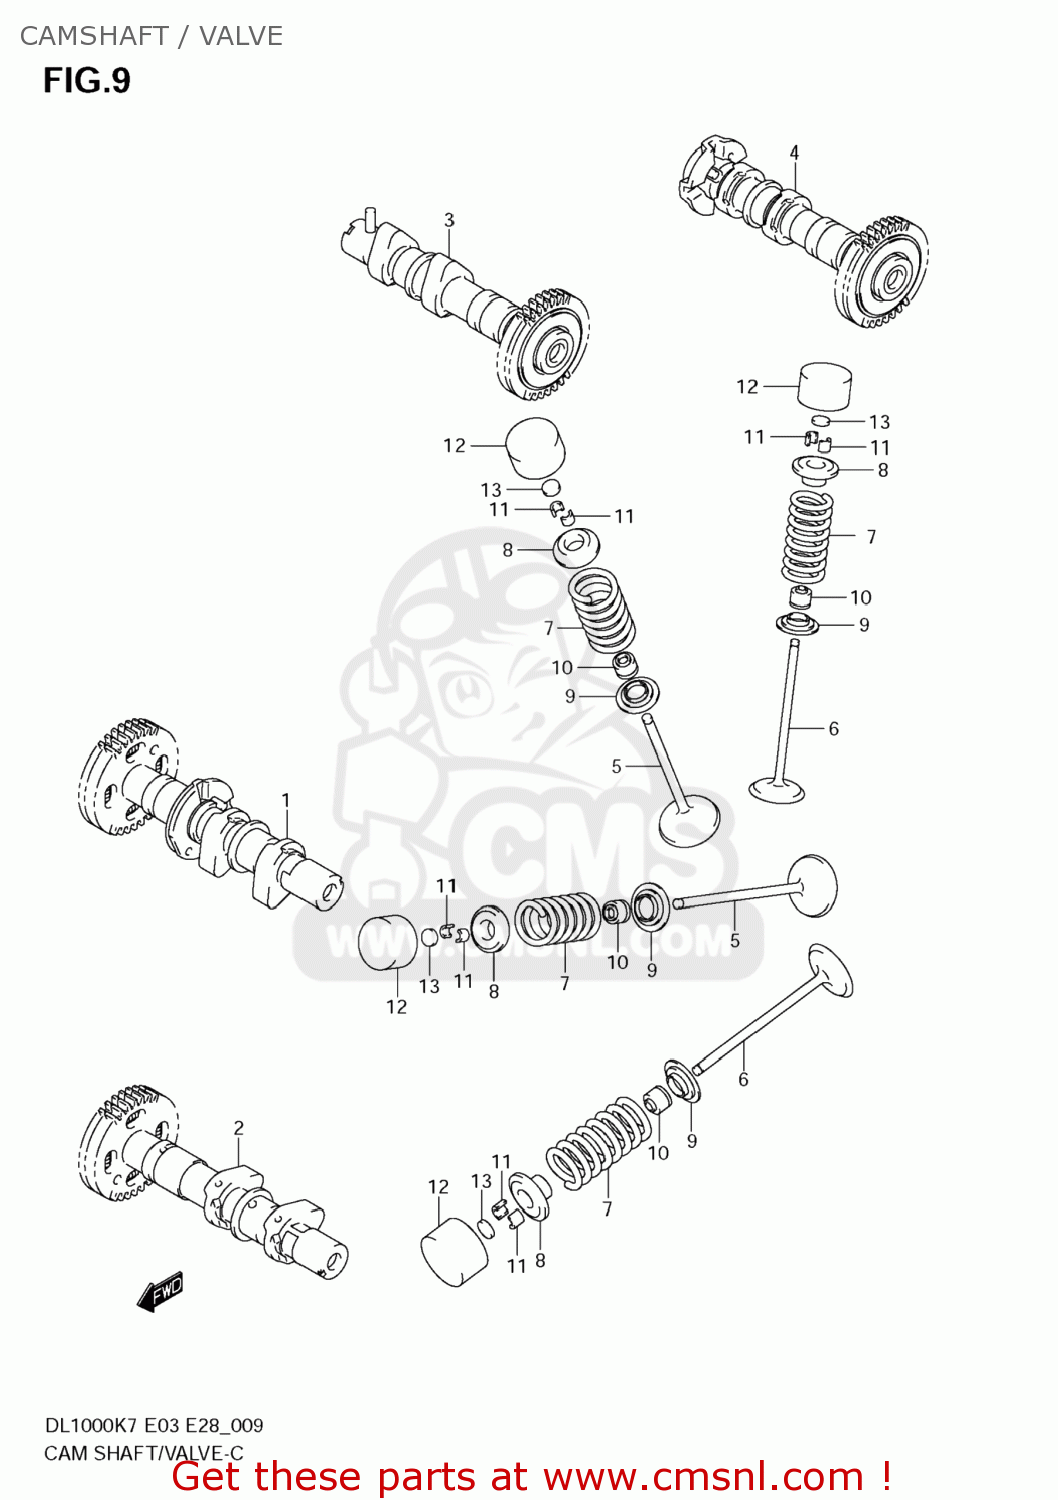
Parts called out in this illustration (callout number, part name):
1	CAMSHAFT ASSY,INTAKE FR
2	CAMSHAFT ASSY,EXHAUST FR
3	CAMSHAFT ASSY,INTAKE RR
4	CAMSHAFT ASSY,EXHAUST RR
5	VALVE,INTAKE
6	VALVE,EXHAUST
7	SPRING,VALVE
8	RETAINER,VALVE SPRING
9	SEAT,VALVE SPRING
10	SEAL,OIL(5.5X11X8.2)
11	COTTER,VALVE
12	TAPPET
13	SHIM,TAPPET(T:2.3)
14	SHIM SET,TAPPET
15	CASE,TAPPET SHIM
